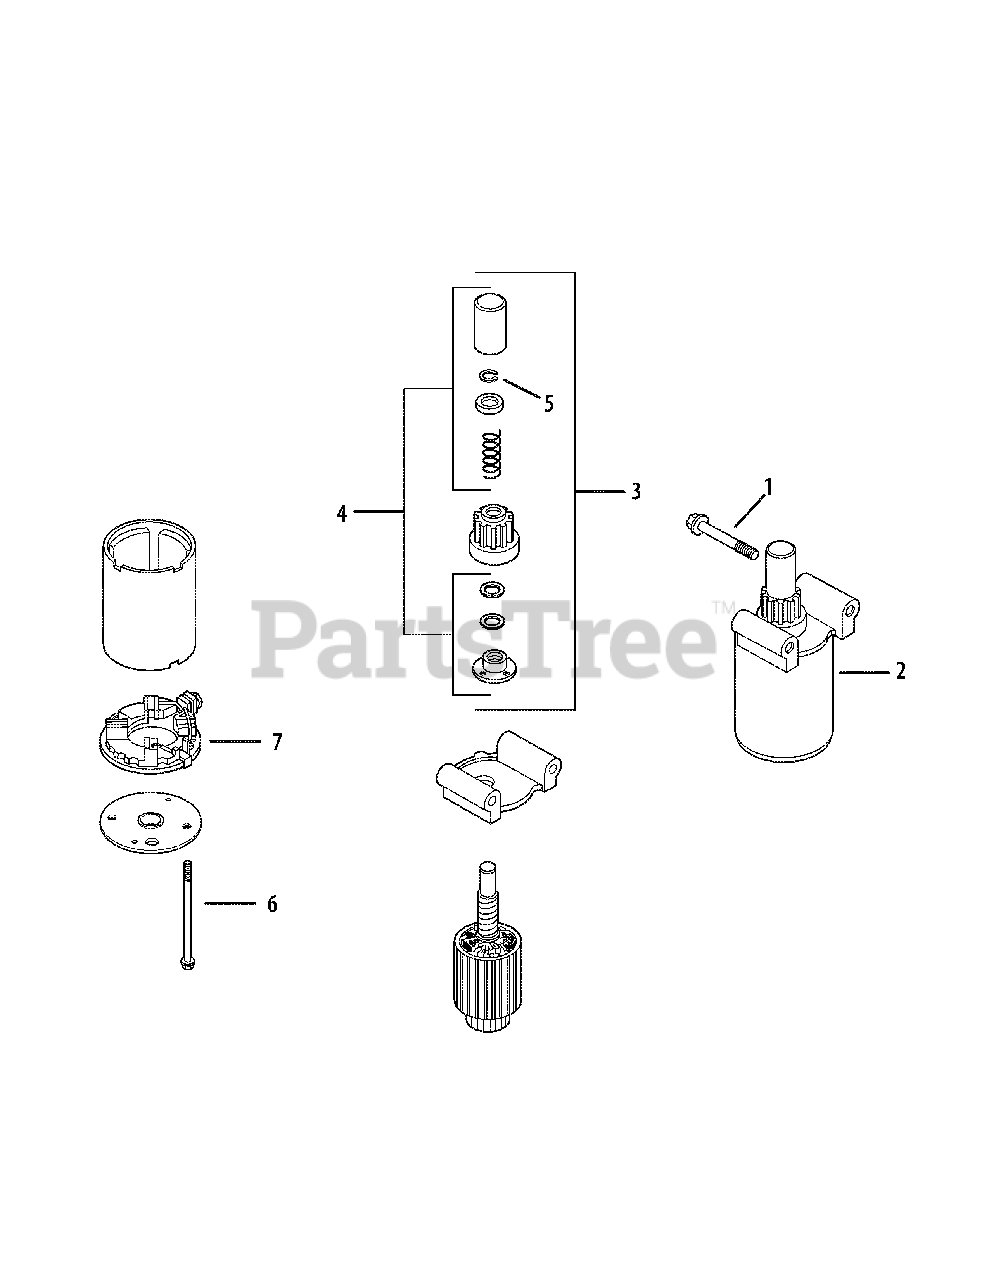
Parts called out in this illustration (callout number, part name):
1	Screw, hex. flange M8x1.25x70
2	Starter assembly
4	Kit, drive parts
5	Retaining Ring
7	Commutator, end cap
